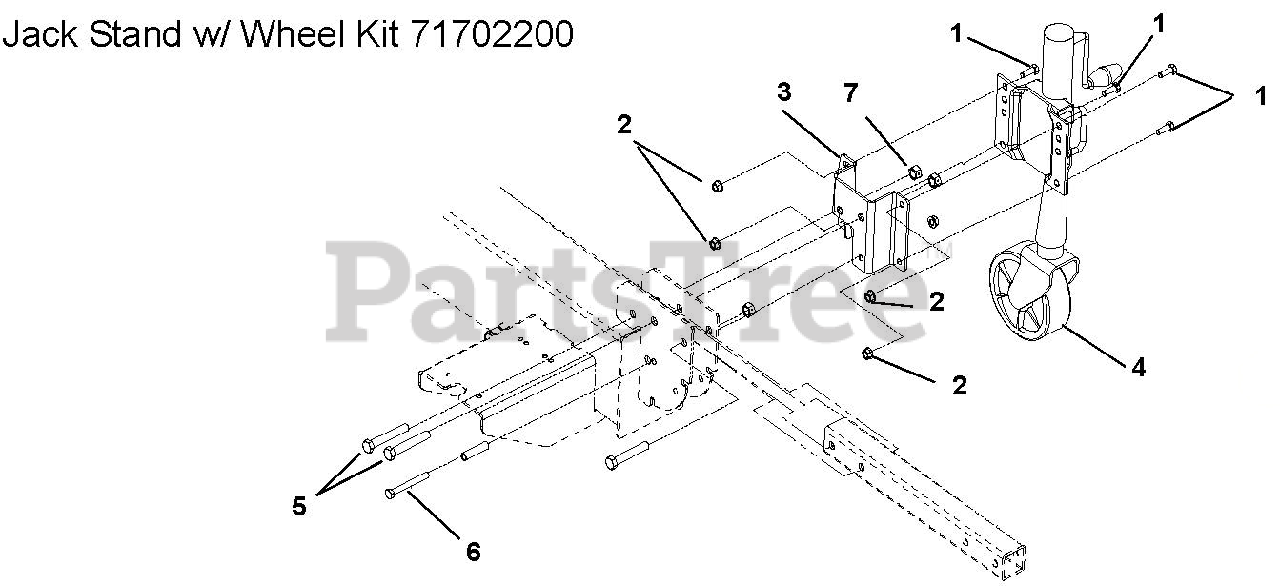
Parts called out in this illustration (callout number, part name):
1	Bolt, Hex .38-16 x 1.00 GR5
2	Nut, Top Flange Locking .38-16
3	Bracket, Mounting
4	Stand, Jack w/Wheel
5	Bolt, Hex .50-13 x 3.25 GR5
6	Bolt, Hex .38-16 x 3.25 GR5
7	Nut, Center Locking .50-13
